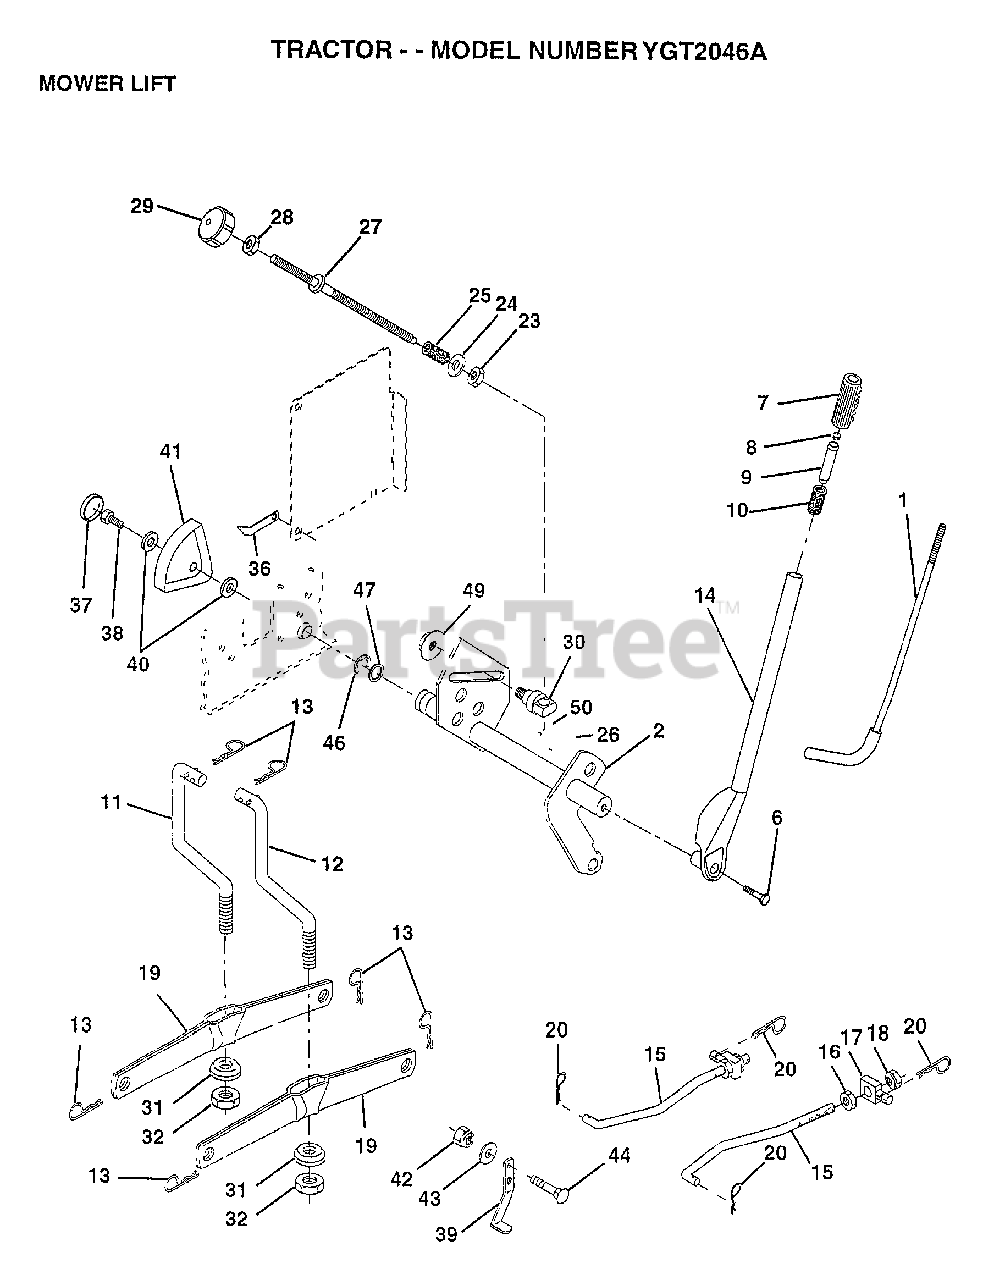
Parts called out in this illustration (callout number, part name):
1	LEVER ROD LT
2	SHAFT LIFT W/IND
6	"BOLT,HEX"
7	GRIP HANDLE
10	SPRING T
11	LINK.LIFT.LH.GTV
12	LINK.LIFT.RH.GTV.
15	LINK.FRONT
16	NUT
17	TRUNION
18	NUT.LK.W/WSH.1/2.
19	ARM SUSP REAR
20	RETAINER.SPRING
23	NUT T
24	WASHER
25	SPRING.COMP.INF.H
27	ROD.ADJ.LIFT
28	NUT
29	KNOB INF 3/8-16
30	TRUNNION
31	BEARING PVT LH
32	NUT.CROWNLOCK.3/8
36	POINTER HEIGHT INDICATOR
37	"PLUG,HOLE"
38	SCREW
39	STOP.OVER.CENTER
40	WASHER
41	HEIGHT INDICATOR
43	WASHER GT
44	BOLT
46	E-RING
47	WASHER
49	NUT.HXFLG.LOCK.
50	NUT PUSH M
